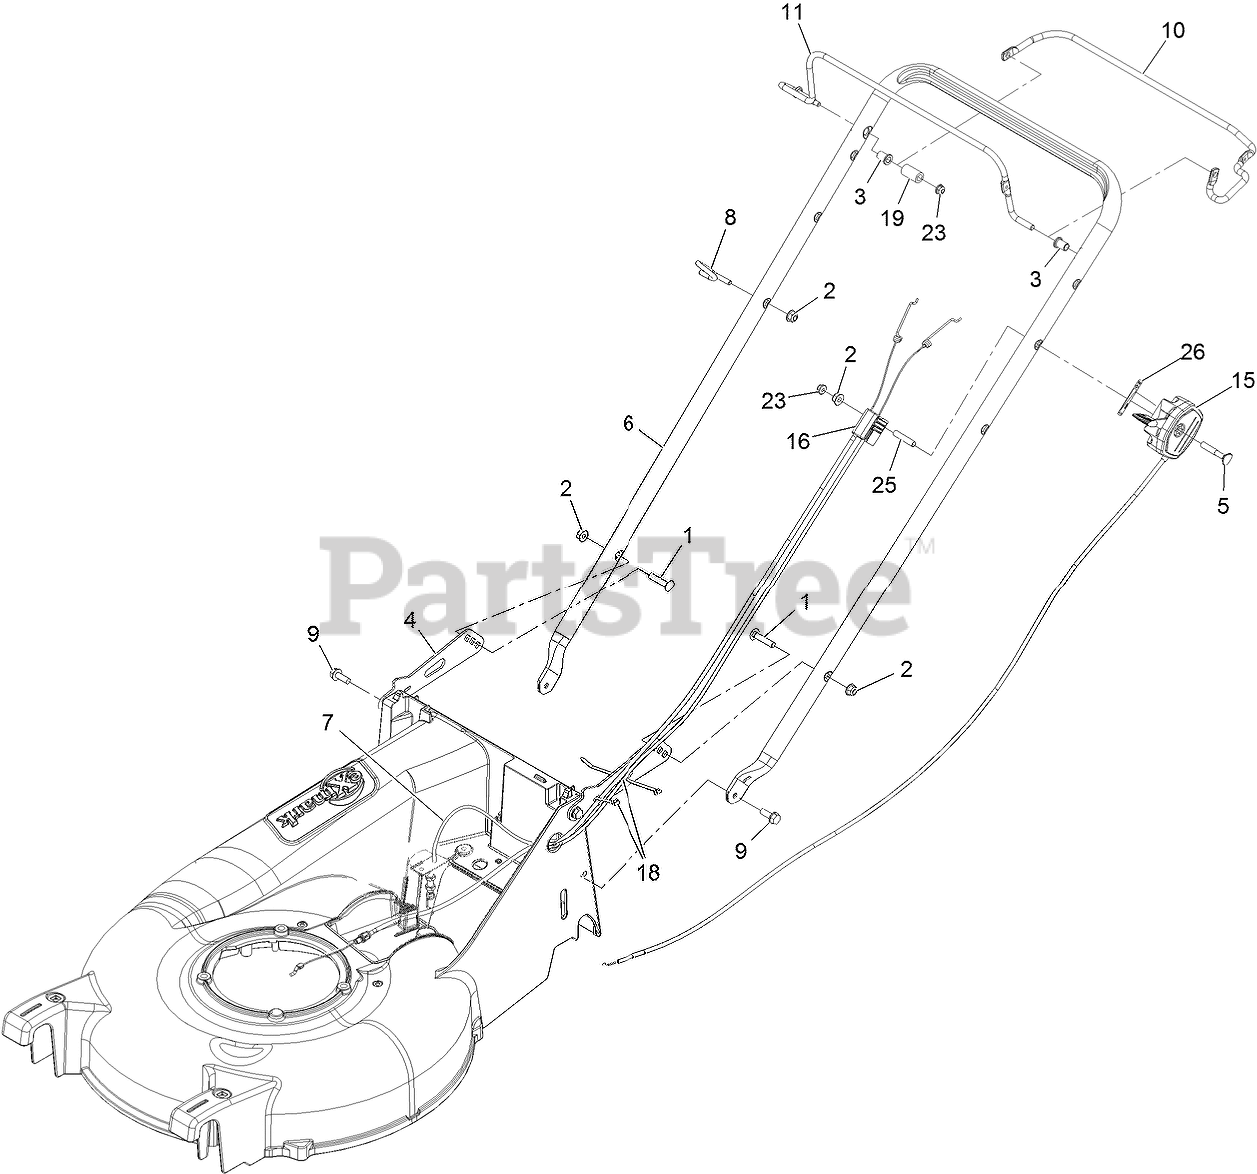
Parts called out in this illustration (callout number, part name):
1	BOLT-CARR
2	NUT-HF, NI
3	BUSHING-HANDLEBAR
4	BRACKET,HANDLEBAR
5	SCREW-HH
6	HANDLEBAR-P21
7	CABLE, DRIVE EC21
8	GUIDE,ROPE
9	SCREW-TAPTITE
10	BAIL-DRIVE COATED
15	CABLE-THROTTLE/CHOKE
16	CABLE-ZONE HONDA
18	TIE-CABLE
25	SPACER-THROTTLE
26	DECAL,THROTTLE/CHOKE
